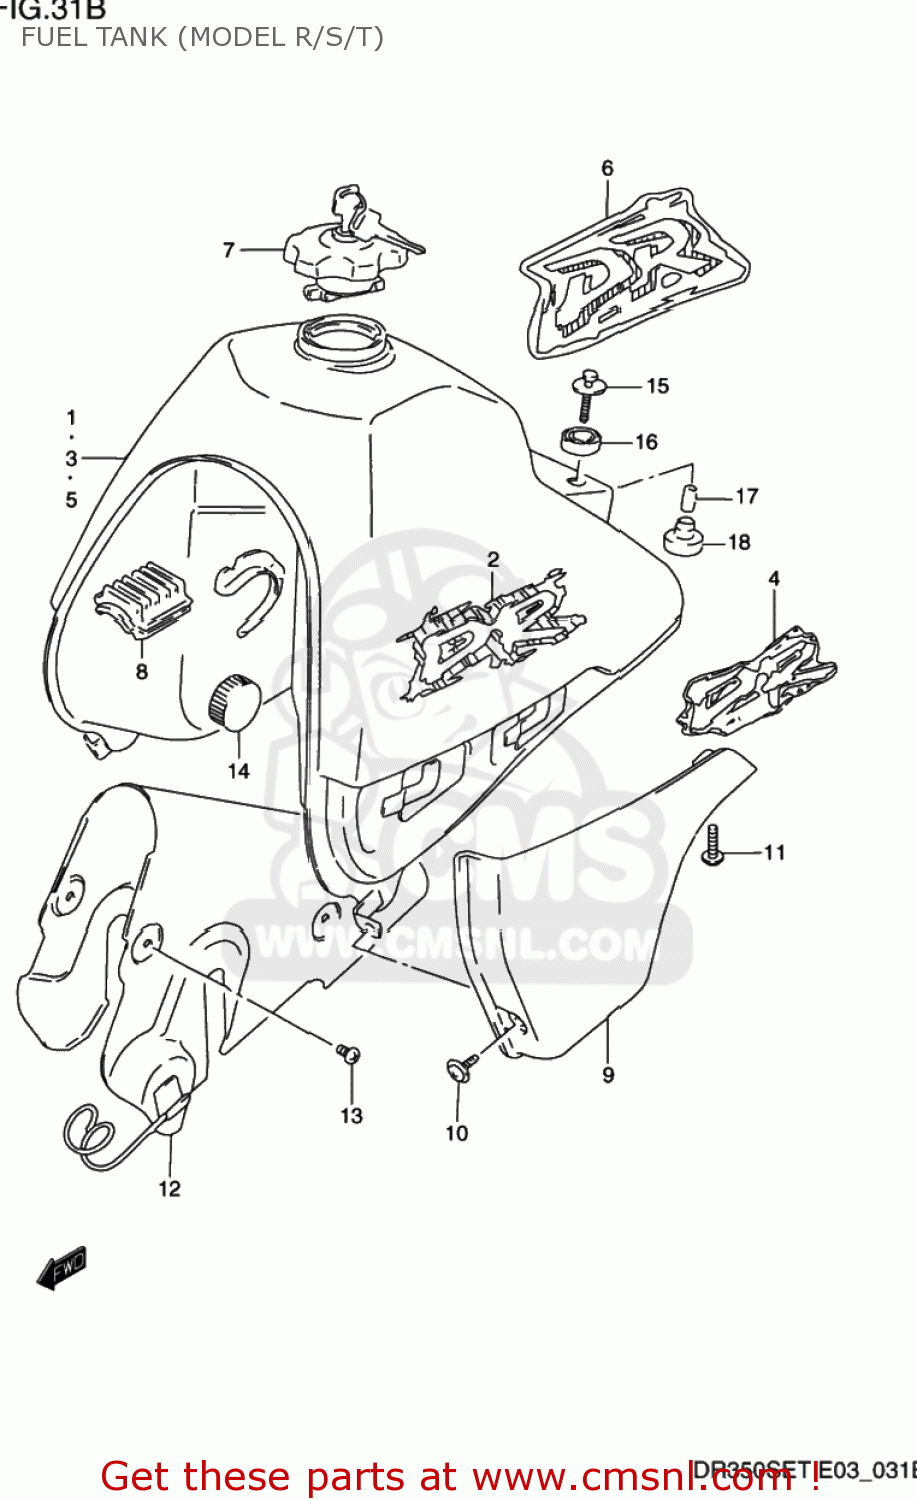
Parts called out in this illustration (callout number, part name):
1	TANK ASSEMBLY,FUEL
2	EMBLEM SET,FUEL TANK
3	TANK ASSEMBLY,FUEL
4	EMBLEM SET,FUEL TANK
5	TANK ASSEMBLY,FUEL
6	TAPE SET,FUEL TANK
7	CAP SET,FUEL TANK
8	CUSHION,FUEL TANK FR UPR
9	COVER,FUEL TANK,R
10	SCREW
11	SCREW(6X12)
12	SHIELD,FUEL TANK
13	BOLT
14	CUSHION
15	BOLT
16	CUSHION
17	SPACER
18	CUSHION
